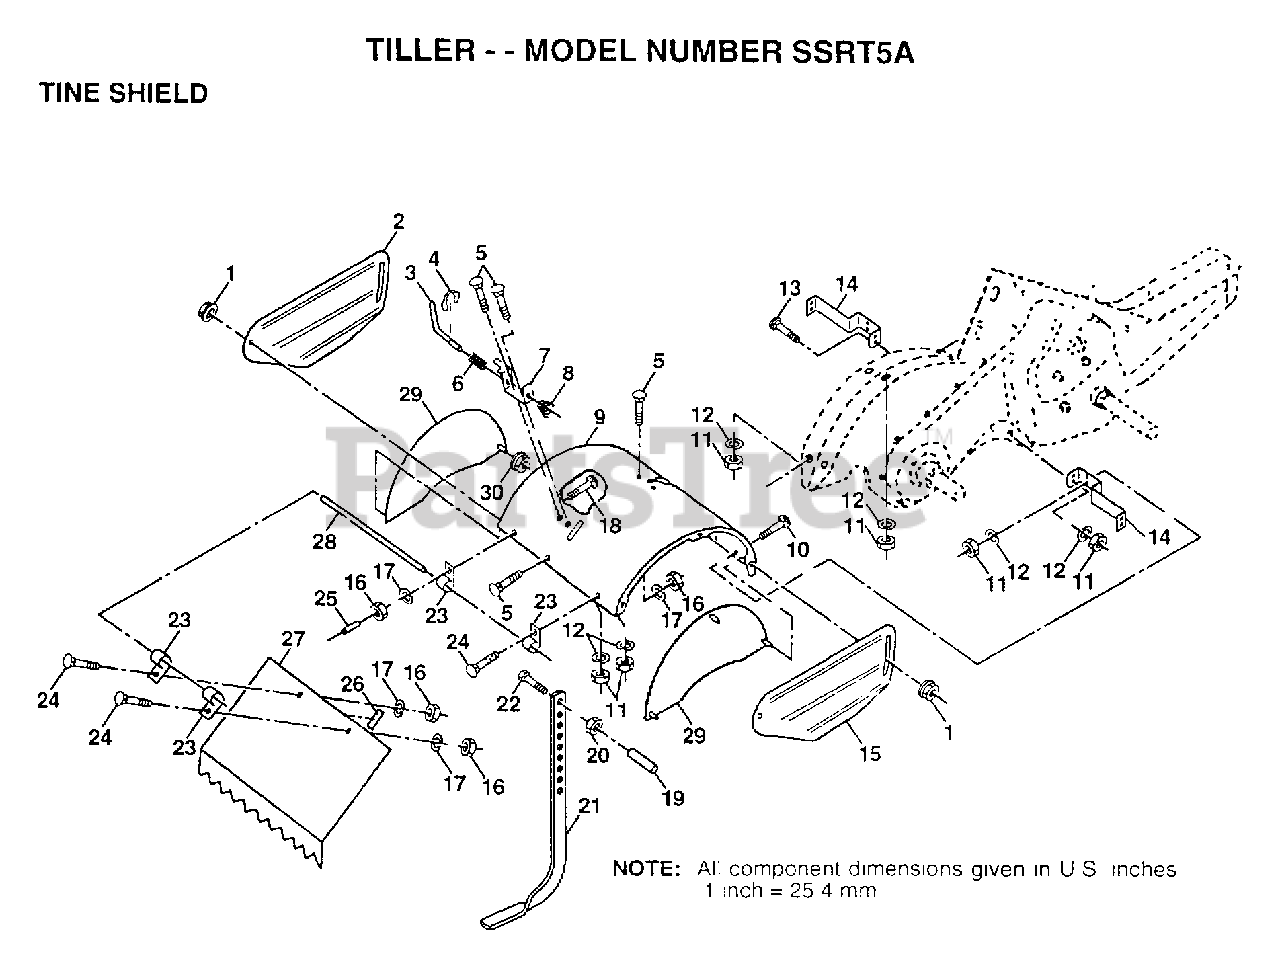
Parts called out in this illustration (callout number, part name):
1	NUT
2	SHIELD.SD.OUT.LH
3	STAKE PIN TI
4	KLIP RING TI
5	BOLT
6	SPRING TI
7	LATCH BRACKET TI
8	SPRING CRT
9	TINE SHIELD
10	BOLT
11	NUT.HEX.5/16-18
12	LOCKWASHER
13	BOLT
14	"BRACKET,SHIELD"
15	SHIELD.SD.OUT.RH
17	LOCKWASHER
18	BOLT
19	GRIP CRT
20	NUT.HEX.3/8-16UNC
22	BOLT
23	HINGE CRT
24	BOLT
25	VINYL CAP TI
26	PAD IDLER TI
27	LEVELING SHIELD
28	PIN HINGE
29	SIDE SHIELD
30	LOCKNUT TI
